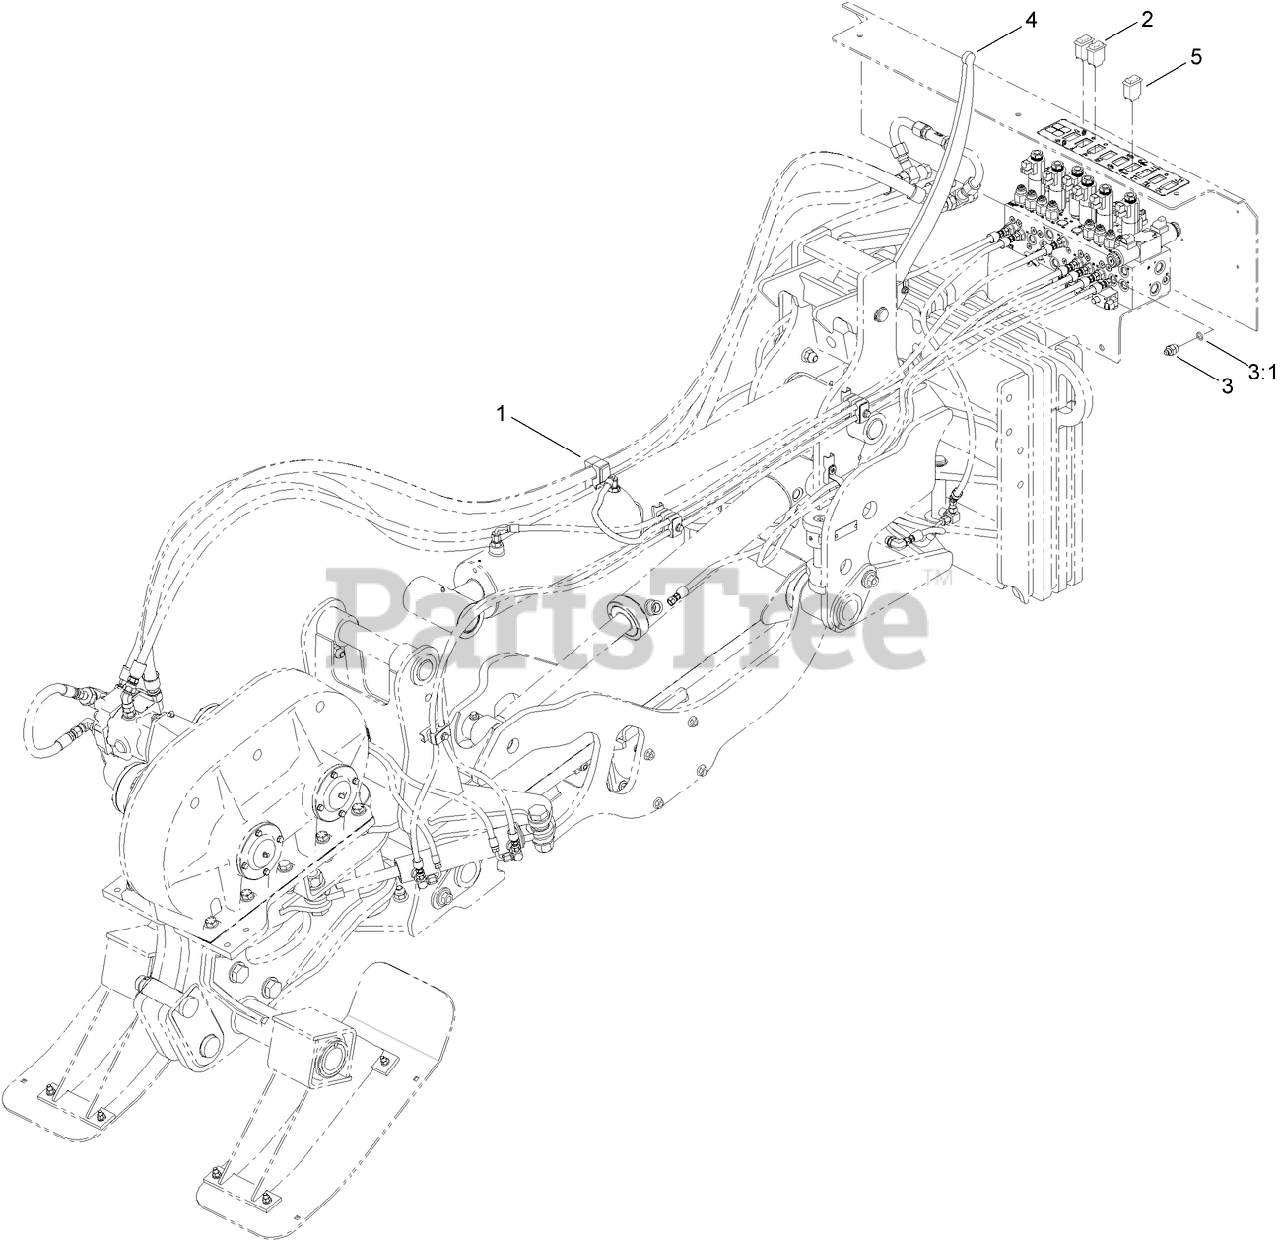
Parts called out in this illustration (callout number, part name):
1	P95 ATTACH KIT
2	SWITCH-ROCKER, 2 POLE (ON/OFF)
3	CONNECTOR
3:1	O-RING
4	PLATE-LATCH
5	SWITCH-ROCKER, 2 POLE
